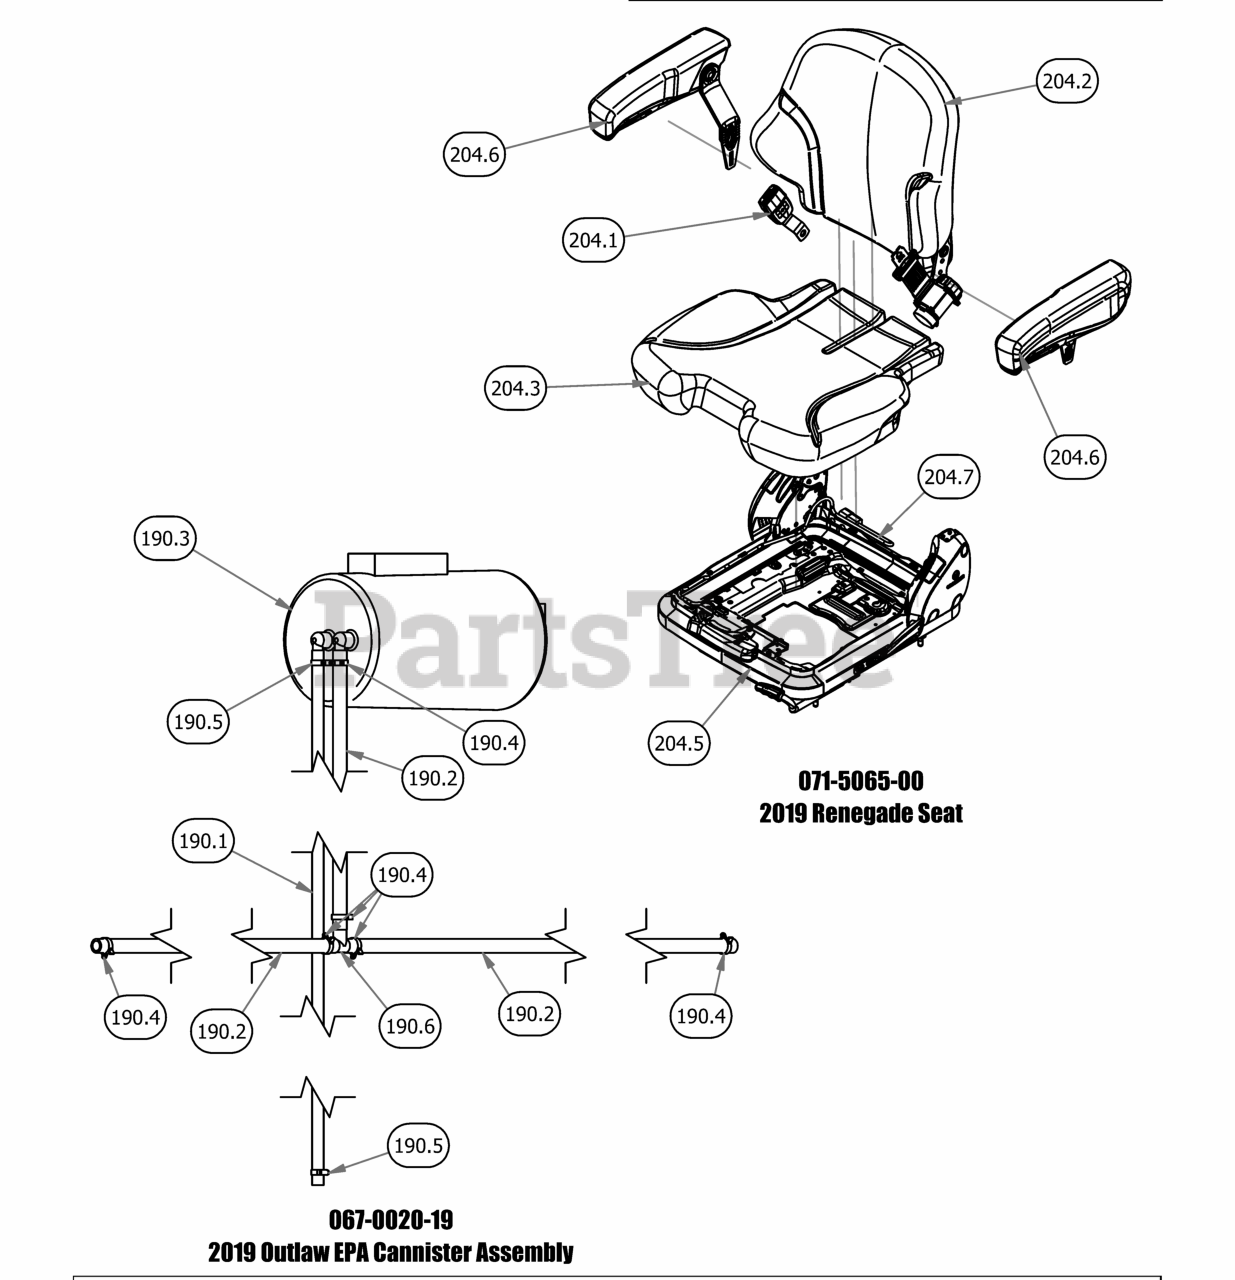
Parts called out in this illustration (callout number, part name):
190.1	3/16" Vinyl Tubing, 66" Long
190.2	1/4" Vinyl Tubing 38" Long
190.3	Carbon Canister
190.4	3/16 Vinyl Clamp
190.5	3/16" Vinyl Hose Clamp
190.6	fuel line T
204.2	Backrest Cushion
204.3	Seat Cushion
204.5	Slave & Adjuster
204.6	Arm Rest Kit
204.7	Seat Switch
